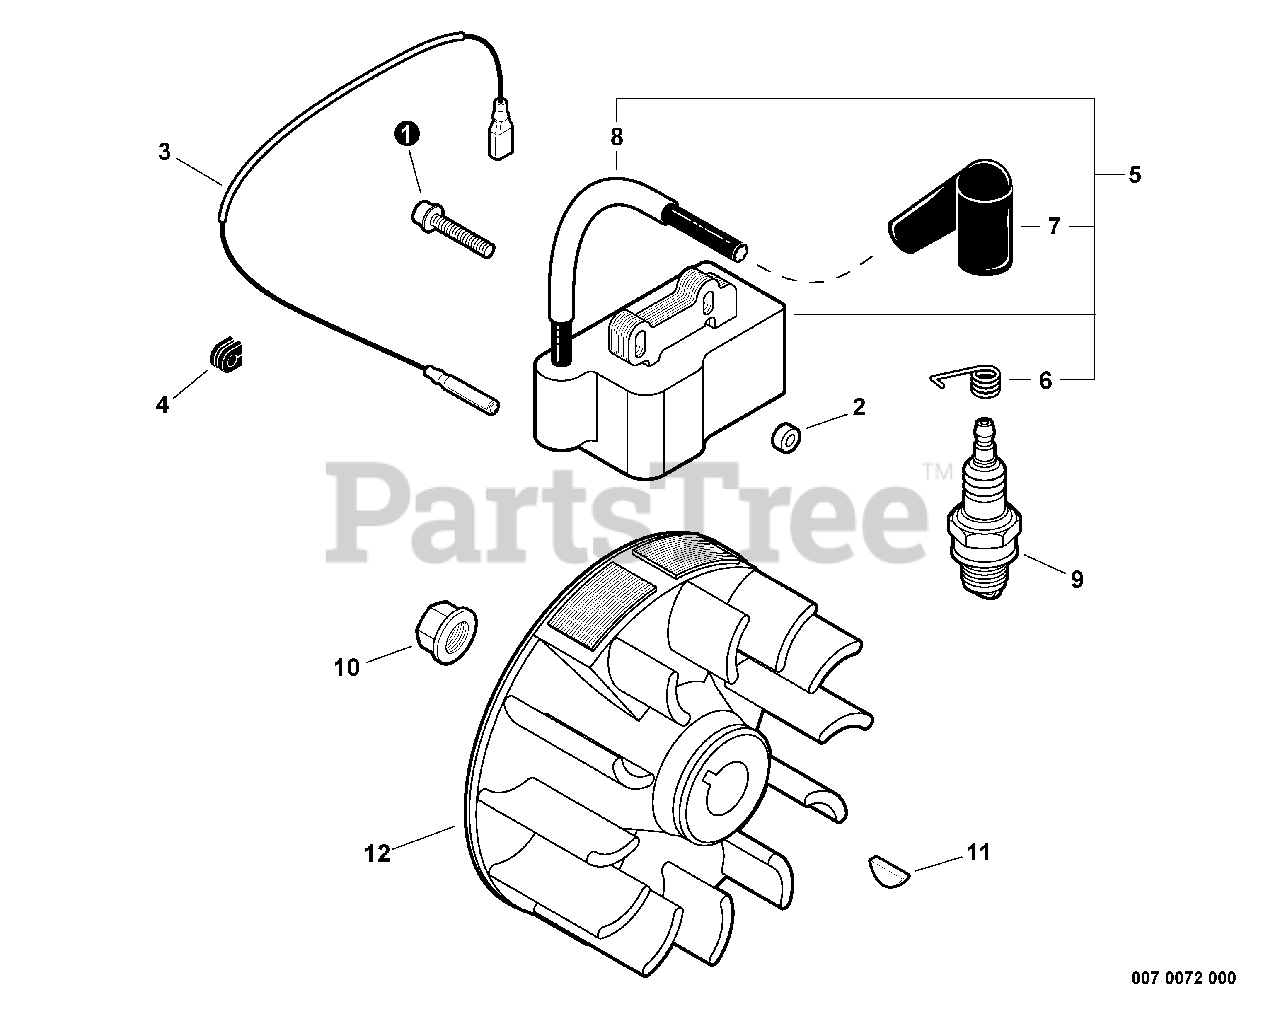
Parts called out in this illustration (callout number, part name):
1	BOLT M4×26
2	INSULATOR 4.2×11×6
3	LEAD - IGNITION
4	GROMMET, LEAD
5	COIL ASSY, IGNITION
6	TERMINAL, SPARK PLUG
7	CAP, SPARK PLUG
8	TUBE, INSULATOR
9	SPARK PLUG - CMR5H
11	KEY, WOODRUFF 3×10
12	FLYWHEEL
